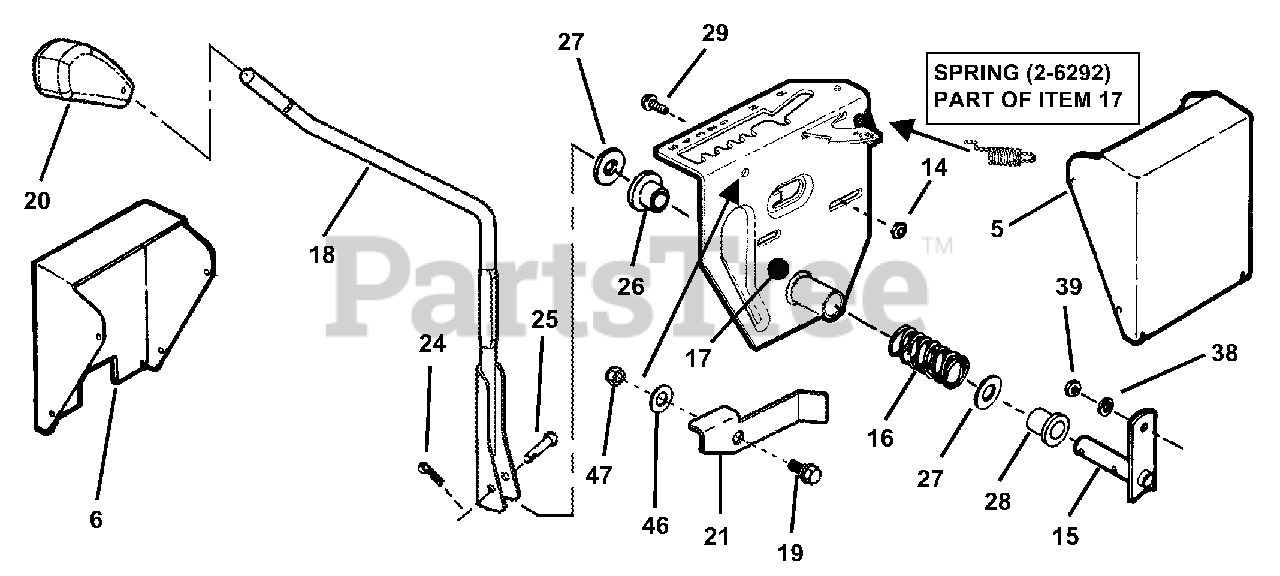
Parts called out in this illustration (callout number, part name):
5	COVER, Battery
6	COVER, Solenoid
14	NUT, 5/16-18 Hex
15	ARM, Shift Handle (Weldment)
16	SPRING, Shift Handle
17	ASSEMBLY, Shift Detent
18	HANDLE, Shift (Weldment)
19	BOLT, 5/16-18 Shoulder
20	KNOB, Shift Handle
21	LEVER, Over-Ride
24	COTTER-PIN, 3/32 x 3/4"
25	PIN, 1/4 x 1-3/4" Tapered Clevis
26	BUSHING, Nylon
27	WASHER, Thrust
28	BUSHING, Nylon
29	SCREW, 5/16-18 x 5/8" Hex Washer Self-Tap
38	WASHER, 5/16" Split Lock
39	NUT, 5/16-24 Hex, Grade 5
46	WASHER, 7/16" Flat
47	NUT, 5/16-18 Nyloc
